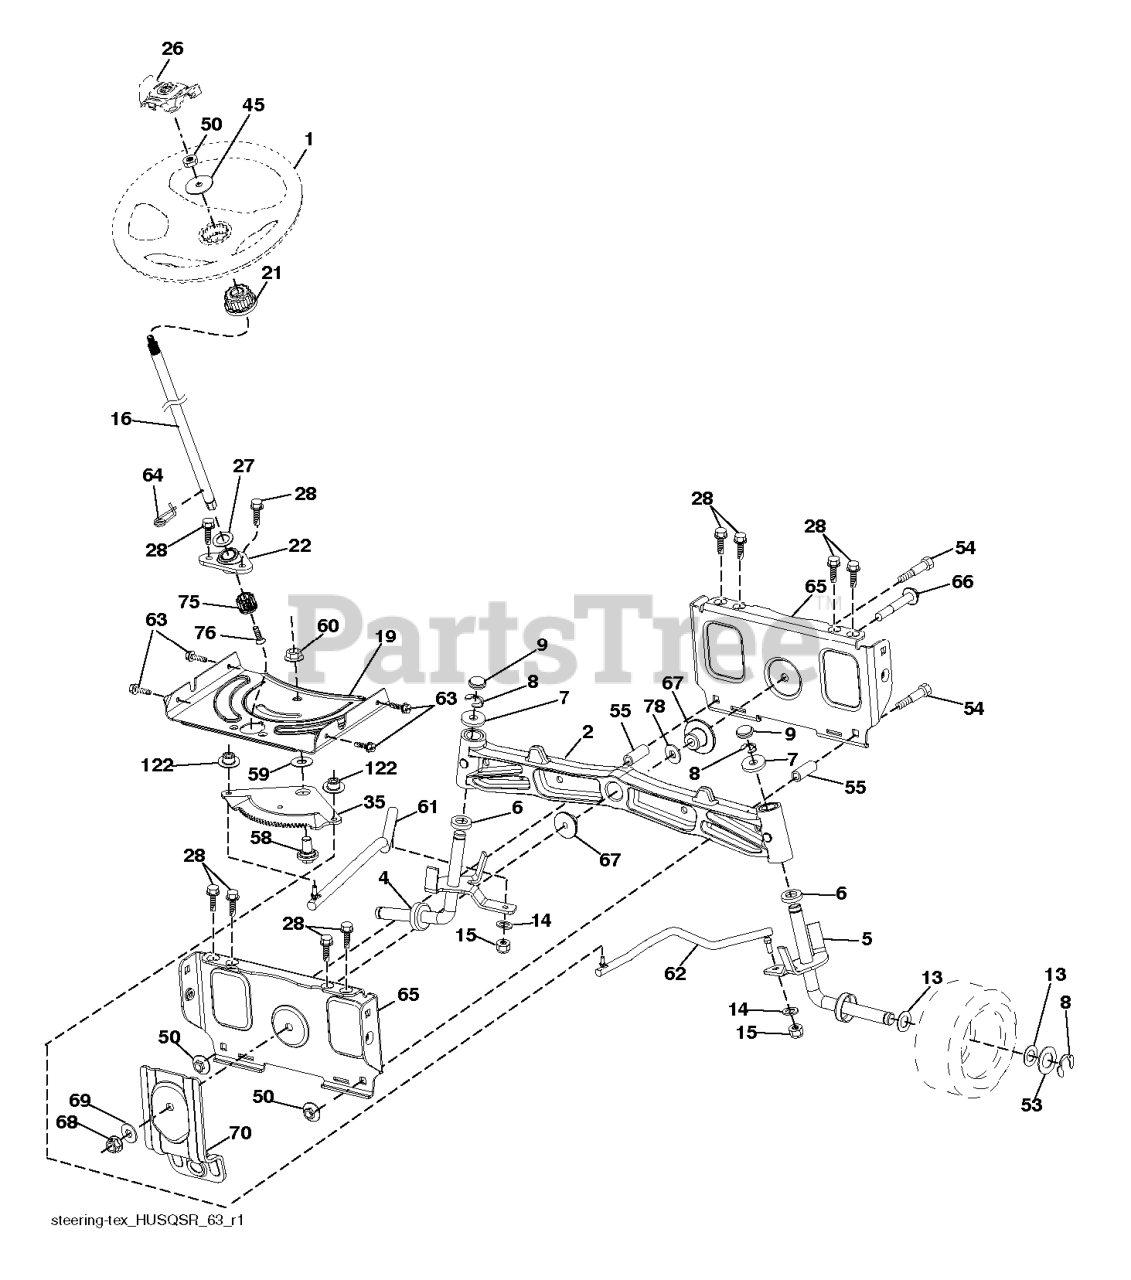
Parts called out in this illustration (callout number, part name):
1	WHEEL.STEER.HUSQ.SR.498.OVMLD
2	AXLE.CAST.IRON
4	SPINDLE.WELDED.LH.16"TEX
5	SPINDLE.WELDED.RH.16"TEX
6	THRUST WASHER
9	CAP.SPINDLE.BLACK
14	SLW 3/8 STD
15	NUT CROWNLOCK 3/8-24
16	SHAFT.STEER.2HIGH.SPLND.PLATED
19	PLATE.STEER.DDL.NLT/NG
21	ADAPTER.WHEEL.STEER.SPLND.ALUM
22	BEARING.SUBASM.SHAFT.STEER.LOW
26	INSERT.CAP.WHL.STRG.HUSQ.PREM
27	WASHER LT
28	SCREW, 3/8-16X3/4
35	GEAR.SECTOR.PLATE.DDL.
45	WASHER.3/8ID.2-3/8OD.12GA.PLTD
50	NUT LOCK FLG 3/8-16 UNC
53	WASHER.HARDENED
55	SPACER.BRACE.AXLE
58	BOLT.SHOULDER.SECTOR.P
59	WASHER.THURST.SECTOR.S
60	NUT FLANGE LOCK 5/8-11
61	DRAGLINK.LH.BALLSTUD.D
62	DRAGLINK.RH.BALLSTUD.D
63	SCREW
64	RETAINER.CLIP.SPRING.S
65	BRACE.AXLE.FRONT.NLT/N
66	BOLT HEX FGHD 7/16-14 X 3 SERR
67	BUSHING.PM.FRONT AXLE
68	NUT.LOCK.FLANGE.7/16
69	WASHER.1.5X.505X.118
70	BRACKET.FRT.DECK.SUSP.RR.MT431
75	PINION.ZINC PLATED
76	SCREW HEAD SOCKET LRVB
78	THRUST WASHER
122	CAP.GEAR.SECTOR.TEX
